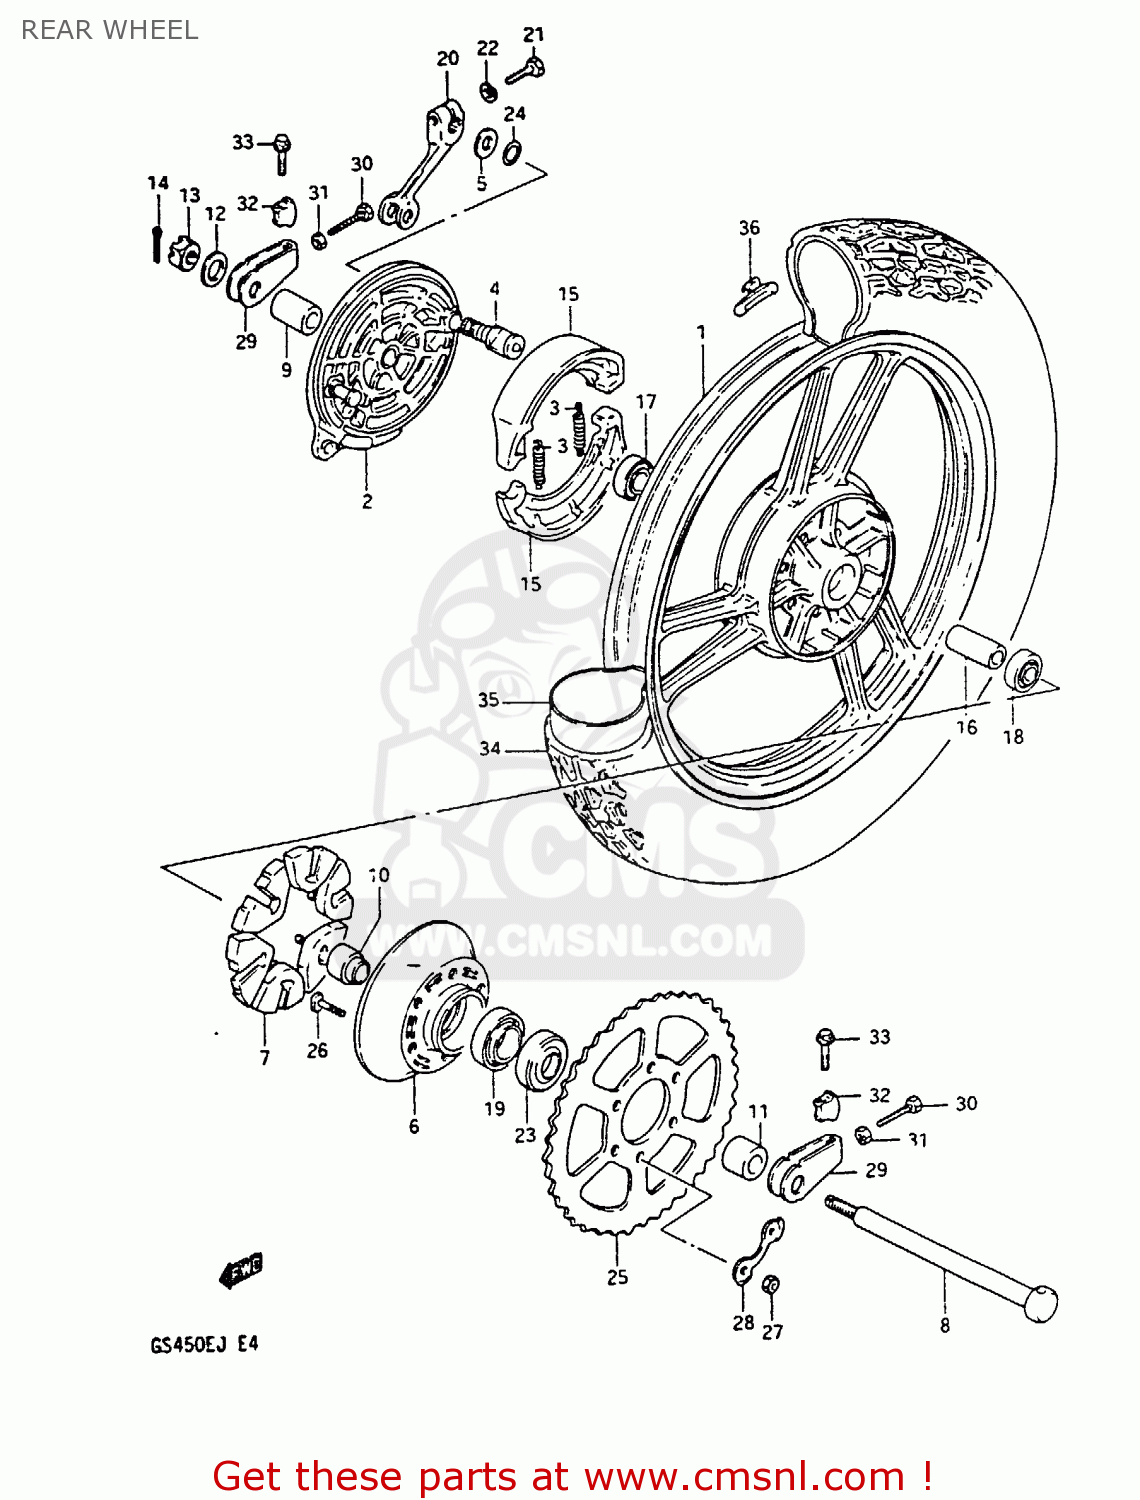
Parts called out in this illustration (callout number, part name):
1	WHEEL, REAR (18X1.85) GOLD
2	PANEL,REAR HUB
3	SPRING,BRAKE SHOE
4	CAM,FRONT BRAKE
5	WASHER (15X24X1.6)
6	DRUM,REAR SPROCKET MOUNT
7	ABSORBER,RR HUB SHOCK
8	AXLE,REAR
9	SPACER(17.5X28X44.8)
10	SPACER,REAR HUB BEARING
11	SPACER(17X30.5X22.3)
12	WASHER (17X30X3.2)
13	NUT
14	PIN,COTTER
15	SHOE,BRAKE
16	SPACER (17.6X24X57)
17	BEARING
18	BEARING
19	BEARING
20	LEVER,RR BRAKE CAM
21	BOLT
22	WASHER,LOCK
23	SEAL,OIL(30.5X52X8)
24	O-RING,BOSS
25	SPROCKET,RR
26	BOLT(10X35.5)
27	NUT
28	WASHER
29	ADJUSTER,CHAIN
30	BOLT 8X50
31	NUT
32	SUPPORTER,CHAIN ADJUST
33	BOLT, UPPER
34	TIRE
35	TUBE,INNER
36	BALANCER,WHEEL
